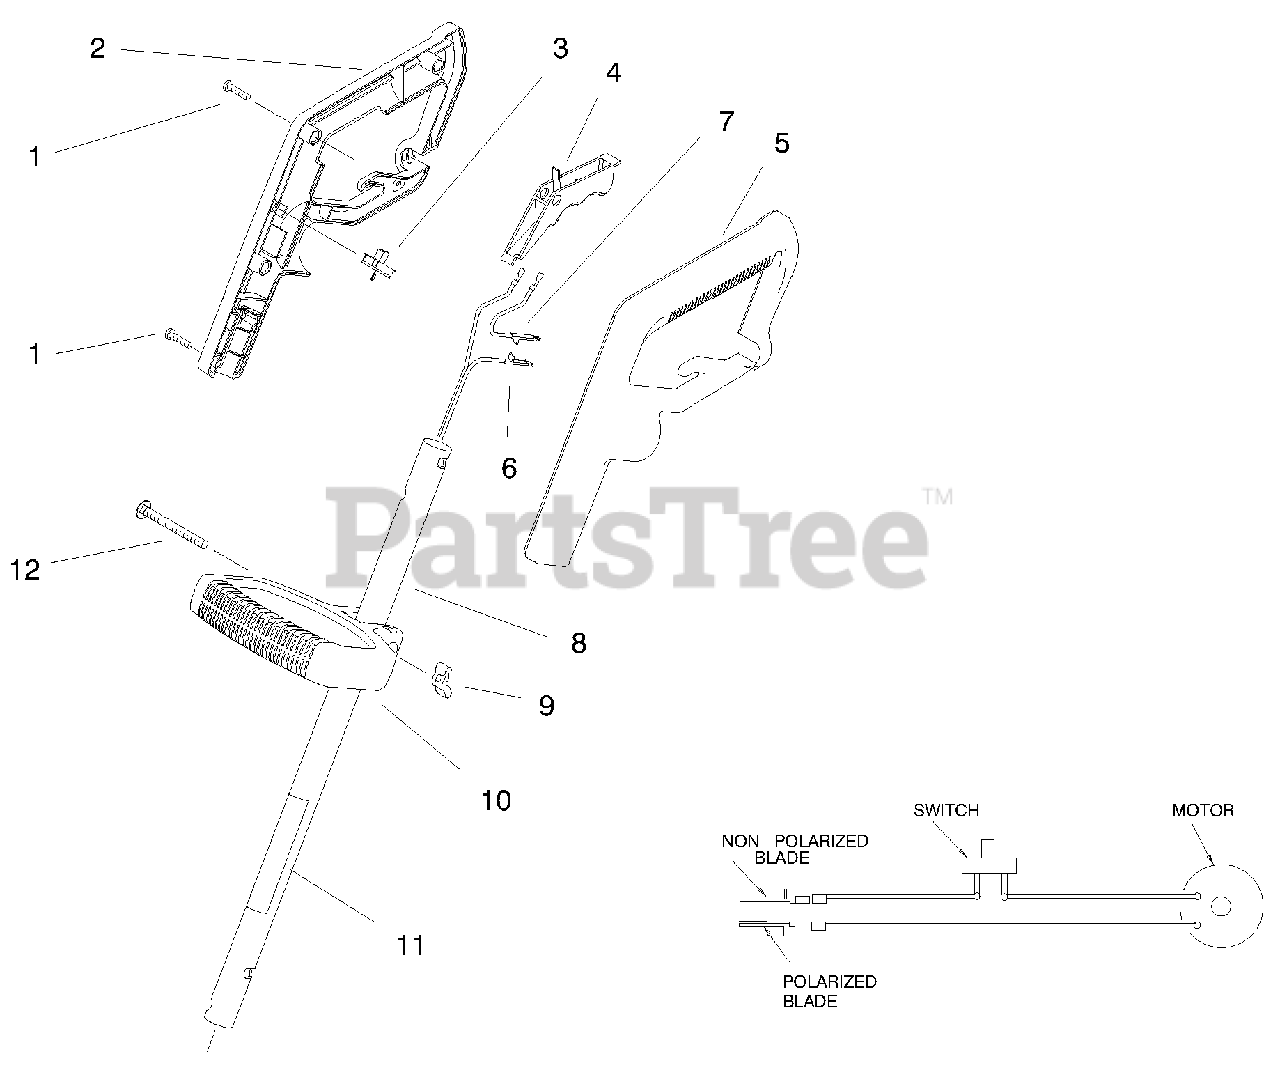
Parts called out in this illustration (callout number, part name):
2	Grip-Hand R.H.
3	Switch-Single Speed
5	Grip-Hand L.H.
6	Harness-Wire
7	ASM-Wire
8	Tube Assembly (Incl. Ref. #11)
10	Handle-Mid
11	Decal-Safety
12	Screw-Carriage
